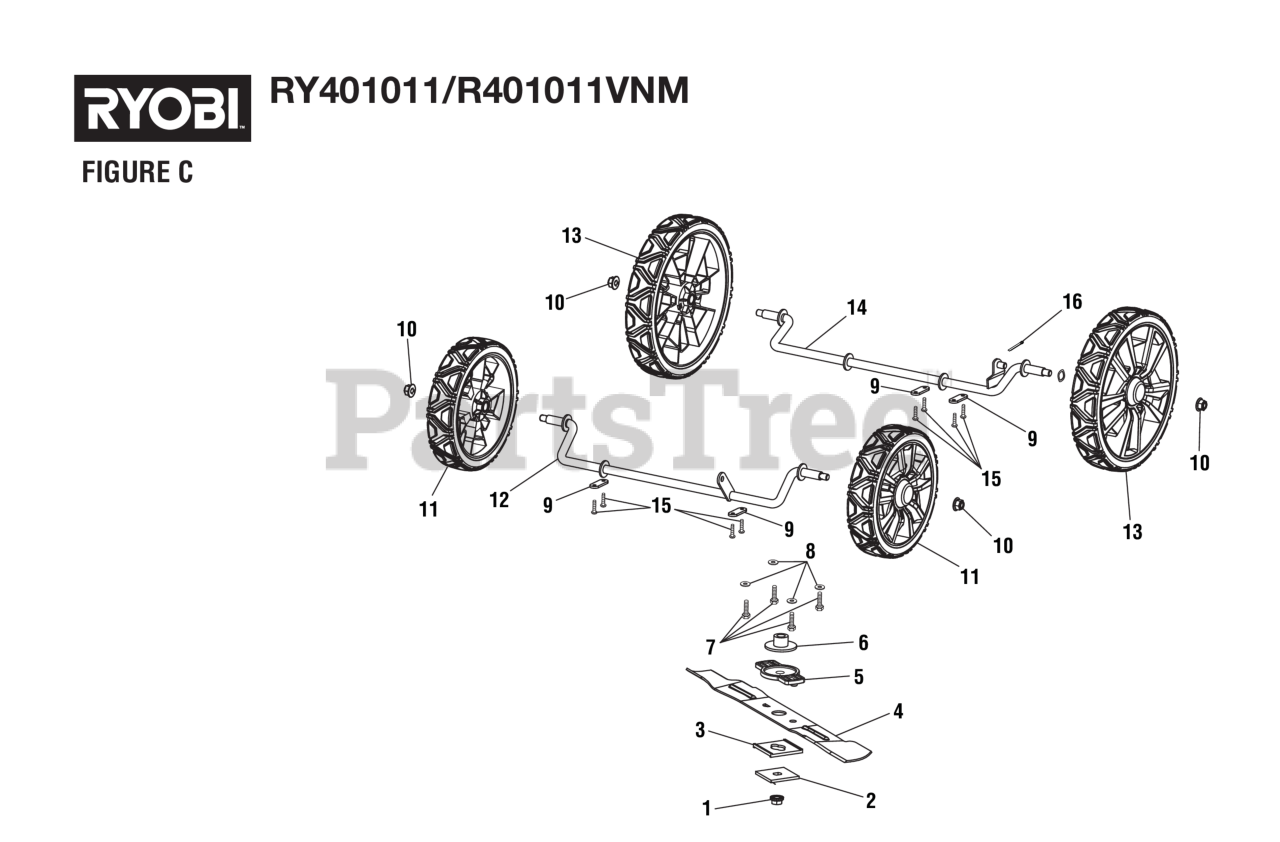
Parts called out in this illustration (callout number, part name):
1	Blade Nut (M10 x 1.25, Hex Flange Hd.)
2	Metal Blade Retainer
4	Bagging Blade
5	Motor Fan Blade Adapter
6	Motor Shaft Bushing
7	Bolt (M6 x 26 mm, Hex Hd.)
8	Washer (ID6.2 x OD15 x 0.08t)
9	Axle Pressure Plate
10	Flange Lock Nut (M8 x 1.25 mm)
11	8'' WHEEL ASSEMBLY
12	Front Axle
13	10"" WHEEL ASSEMBLY
14	Rear Wheel Axle
15	Screw (M4 x 20 mm, T20 Torx Pan Hd. S.T.)
16	Cotter PinÏ? (2.5)
